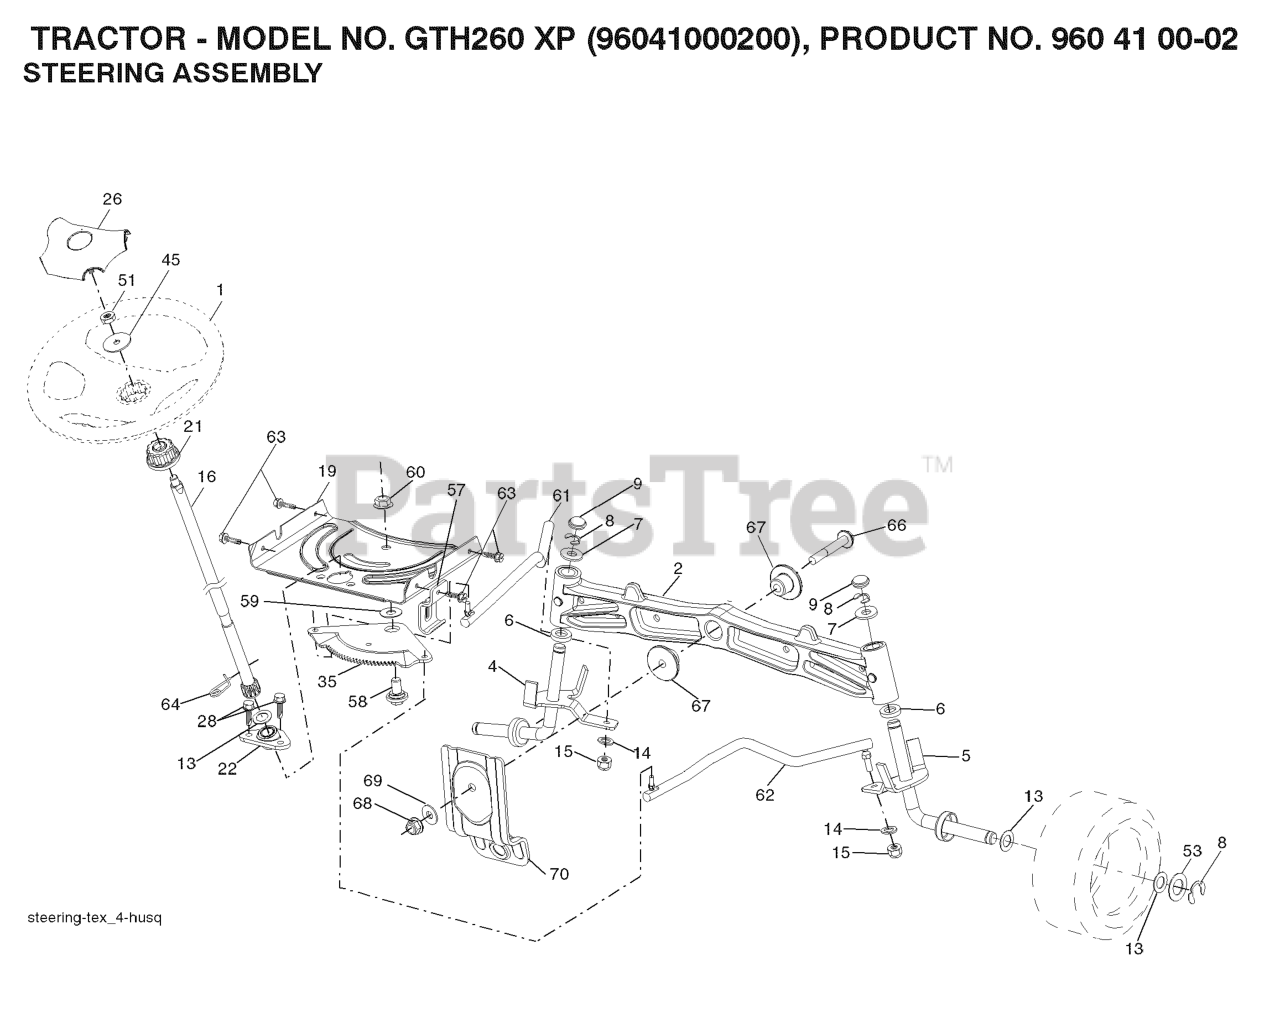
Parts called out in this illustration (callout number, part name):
1	STEERING WHEEL
2	AXLE.CAST.IRON
4	SPINDLE.ASM.LH.DDL.GT
5	SPINDLE.ASM.RH.DDL.GT
6	THRUST WASHER
9	CAP.SPINDLE.BLACK
14	WASHER, LOCK 3/8
15	NUT CROWNLOCK 3/8-24
16	SHAFT.STEER.STEALTH.DD
19	PLATE.STEER.DDL.NLT/NG
21	ADAPTER, WHEEL STNG..
22	BUSHING.ASM.STEERING.A
26	INSERT.CAP.STRG.WH.GRAY
28	SCREW, 3/8-16X3/4
35	GEAR.SECTOR.PLATE.DDL.
45	WASHER 9/16"ID, 2 3/8"OD
51	NUT.HEX.1/2-20
53	WASHER.HARDENED
57	BRKT.UPSTOP.GT/LT.TEX
58	BOLT.SHOULDER.SECTOR.P
59	WASHER.THURST.SECTOR.S
60	NUT FLANGE LOCK 5/8-11
61	DRAGLINK.LH.BALLSTUD.D
62	DRAGLINK.RH.BALLSTUD.D
63	SCREW
64	RETAINER.CLIP.SPRING.S
66	BOLT HEX FGHD 7/16-14 X 3 SERR
67	BUSHING.PM.FRONT AXLE
68	NUT.LOCK.FLANGE.7/16
69	WASHER.1.5X.505X.118
70	BRKT.DECK.SUSPENSION.F
